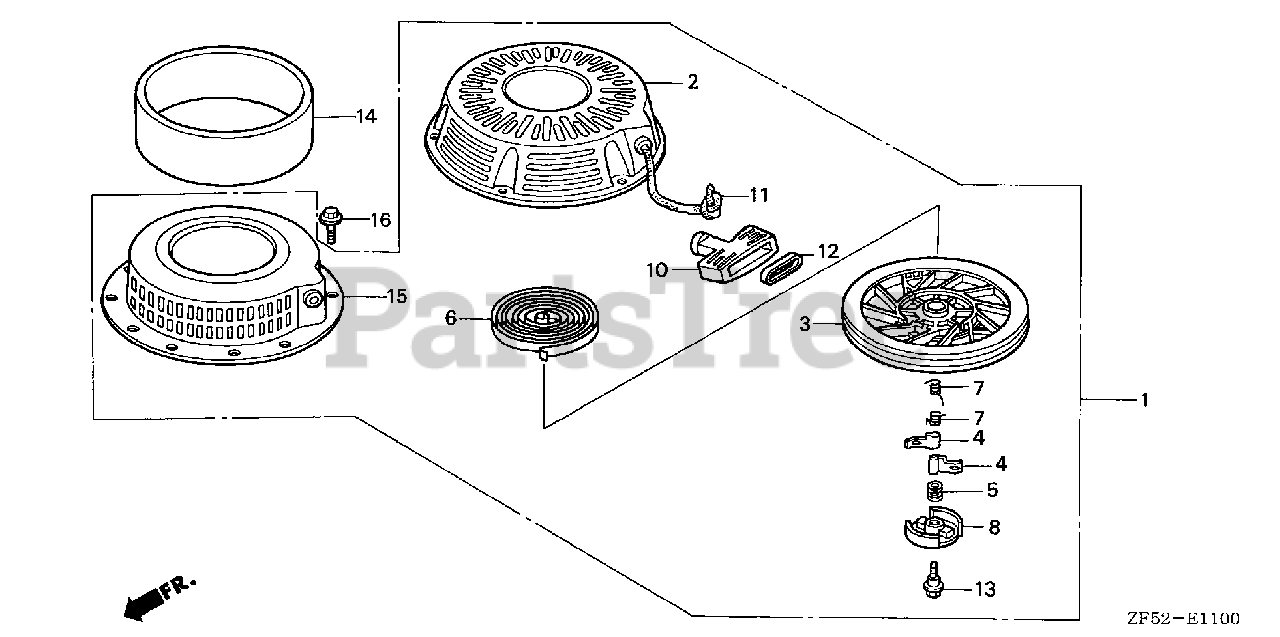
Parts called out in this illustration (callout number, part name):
1	STARTER ASSY., RECOIL *R280* (POWER RED)
3	PULLEY, RECOIL STARTER
4	RATCHET, STARTER
5	SPRING, FRICTION
6	SPRING, STARTER RETURN
7	SPRING, RATCHET
8	RETAINER, SPRING
10	GRIP, STARTER
11	ROPE, RECOIL STARTER
12	GRIP, REINFORCEMENT
13	SCREW, CENTER
14	FILTER, AIR
15	CASE, RECOIL STARTER *R280* (POWER RED)
16	BOLT, FLANGE (6X10)
